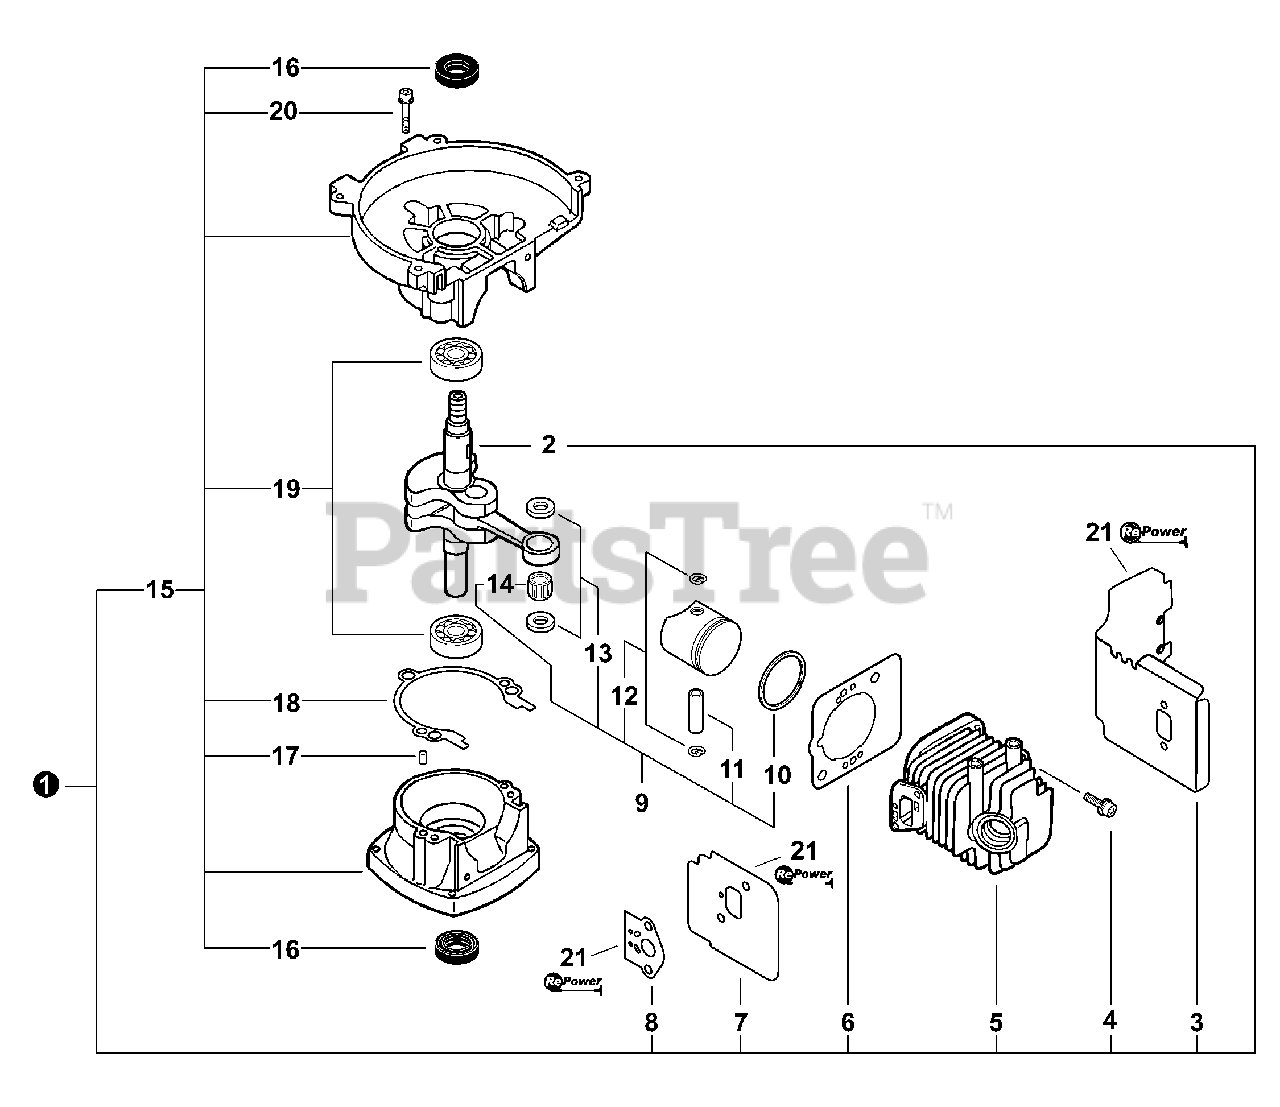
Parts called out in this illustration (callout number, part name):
1	SHORT BLOCK -- SB1075
2	CRANKSHAFT ASSY
3	SHIELD, EXHAUST
4	SCREW - 5×22
5	CYLINDER
6	GASKET, CYLINDER
7	GASKET, INTAKE
8	GASKET, INTAKE
9	PISTON KIT
10	RING, PISTON
11	PIN, PISTON
12	RING, RETAINING
14	BEARING, NEEDLE - 8
15	CRANKCASE KIT
16	SEAL, OIL
17	PIN, LOCATING
18	GASKET, CRANKCASE
19	BEARING, BALL - 6201
20	SCREW - 5×28
21	GASKET KIT
